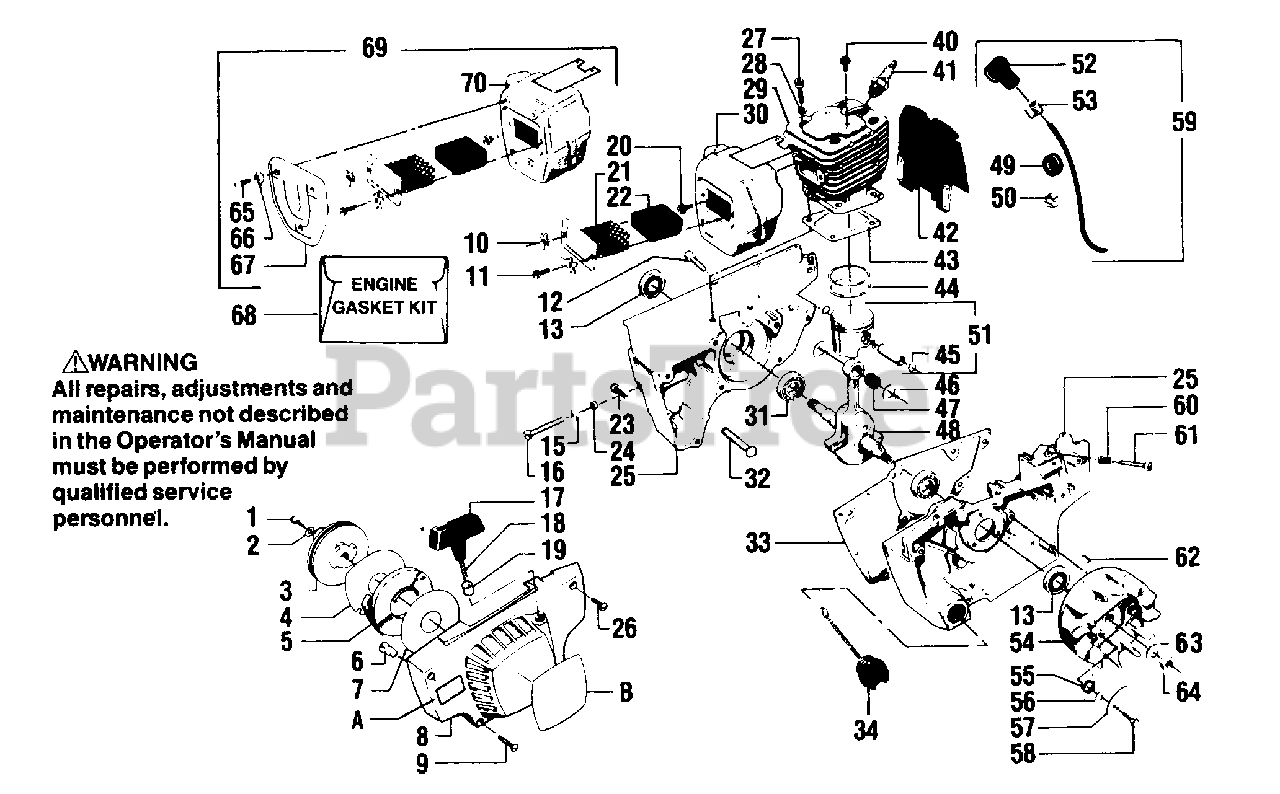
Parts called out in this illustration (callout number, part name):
1	Screw - 1/4 - 20 x 1/2 - Socket Hd.
2	Washer - Starter Pulley
3	Pulley Starter
4	Disc. - Starter - Top
5	Spring - Starter Rewind
6	Pin - Spring Anchor
7	Disc. - Starter - Bottom
8	Fan Housing Ass'y. (Incl. #6 & 19)
9	Screw - Fan Hsg. Mfg. - 1/4 - 20 x 13/16 - Socket Head
10	Retainer - Diffuser Mounting Screw
11	Screws - 10 - 32 x 1/2 - Slotted Hex Hd.
12	Screw - Crankcase #10 - 24 x 3/4 - Socket Head
13	Seal - Crankshaft
15	Pin - Bar Adjusting
16	Screw - Bar Adj. - #10 - 24 x 2-3/16
17	Handle - Starter Rope
18	Rope Kit
19	Bushing - Rope Grommet
20	Screw - Muffler Mfg. 12 - 24 x 5/8
21	Diffuser - Muffler
22	Screen - Spark Arrestor
23	Screw - 6 - 40 x 1/2 - Socket Head
24	Nut - Bar Adj. - #10 - 24 - Self Locking
25	Crankcase Ass'y (Incl. #13, 15, 16, 23, 24, 31 & 32)
26	Screw - Fan Hsg. Mfg. - 1/4 - 20 x 1-1/8 Socket Head
27	Screw - Cylinder - 1/4 - 20 x 1 Socket Hd.
28	Lockwasher - Cylinder
29	Cylinder
30	Ass'y. - Muffler
31	Bearing - Crankshaft
32	Kit - Bar Stud Replacement
33	Gasket - Crankcase
34	Oil Cap Ass'y. (Incl. "O" Ring)
40	Screw - Cylinder Cover Bracket
41	Spark Plug (CJ-8)
42	Air Baffle Assembly
43	Gasket - Cylinder
44	Piston Ring
45	Retainer - Piston Pin
46	Washer - Thrust (Rod Top)
47	Bearing - Top Rod
48	Crankshaft & Rod Assembly (Incl.#36 from page 3)
49	Grommet - Lead Wire
50	Clip - High Tension Lead
51	Piston Assembly - (Incl.#45 & pin)
52	Boot - Spark Plug
53	Connector - Spark Plug
54	Flywheel
55	Spring - Starter Dog
56	Washer - Starter Dog
57	Dog - Starter
58	Stud - Starter Dog
59	High Tension Lead Ass'y. - Ignition (Incl.#52 & 53)
60	Spring - Idle Adj. Screw
61	Screw Adj.-Idle Speed
62	Key - Flywheel
63	Washer - Flywheel Mtg. - 3/8
64	Locknut - Flywheel Mounting - 3/8 - 24
65	Hex Socket Cap Screw - 1/4 - 20 x 5/8 - (Optional)
66	Washer - Conical (Optional)
67	Heat Shield (Optional)
68	Kit - Engine Gasket (Inc. 33,43,49))
69	Muffler Heat Shield (Optional) (Incl.#65, 66, 67 & 70)
70	Hex Fastener & Muffler Ass'y. (Optional)
A	Decal Professional User
B	Decal - Fan Housing
